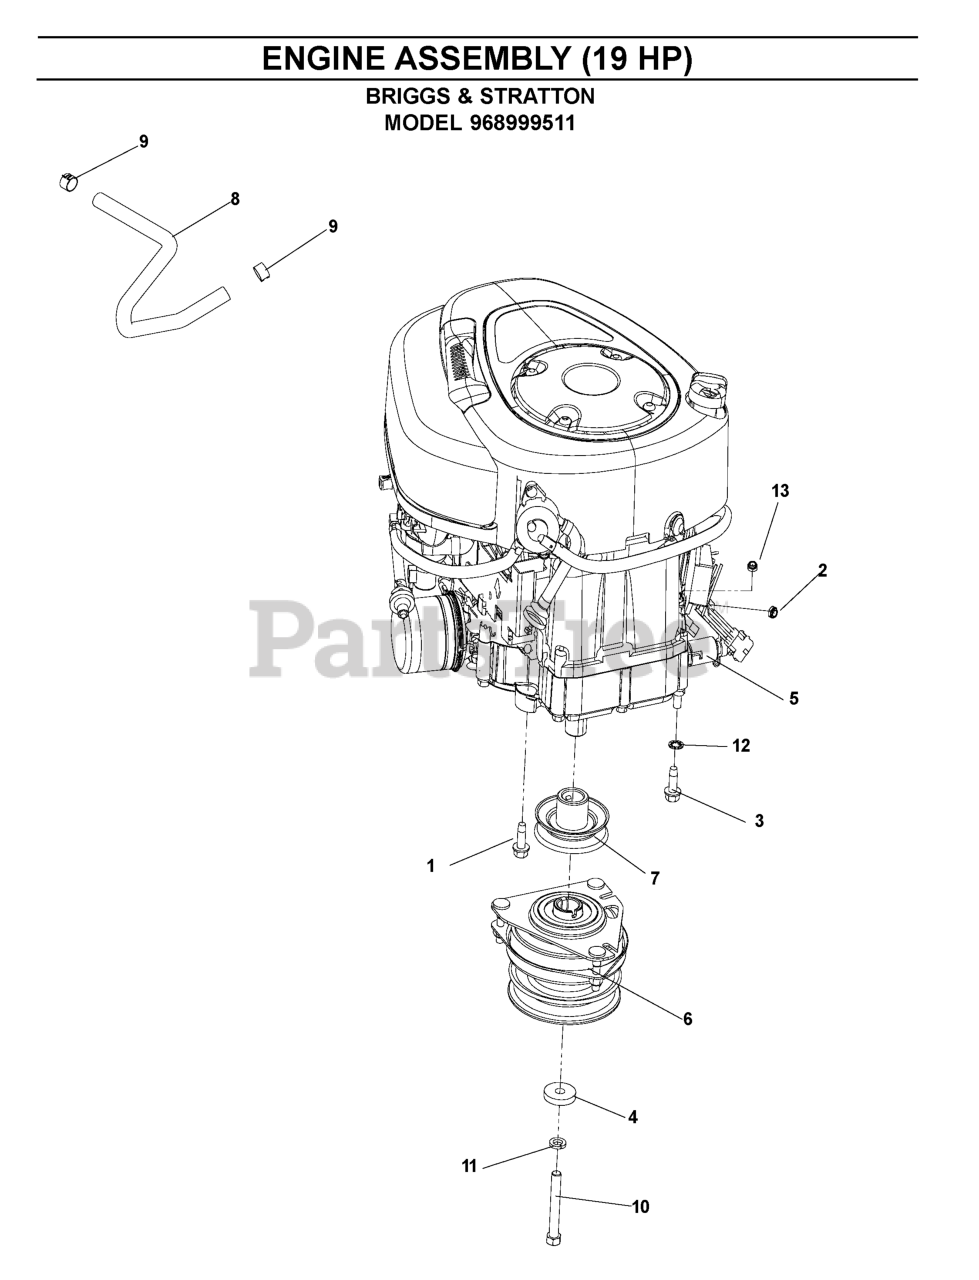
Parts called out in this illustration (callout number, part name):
1	BOLT 3/8-16 X 1.0
2	JAM NUT 1/4C (2 2 PW01)
3	BOLT 3/8-16 X 1 1/2 ZINC CLEAR
4	CLUTCH, WASHER
5	OIL DRAIN FITTING
6	CLUTCH 90 FT/LB OGURA
8	FUEL LINE 5"
9	HOSE CLAMP
10	HEX SCREW 7/16-20 X 3
11	WASHER 7/16 LOCK
12	WASHER, 3/8 ITLW ZN
13	NUT 3/8C CENTERBLOCK
